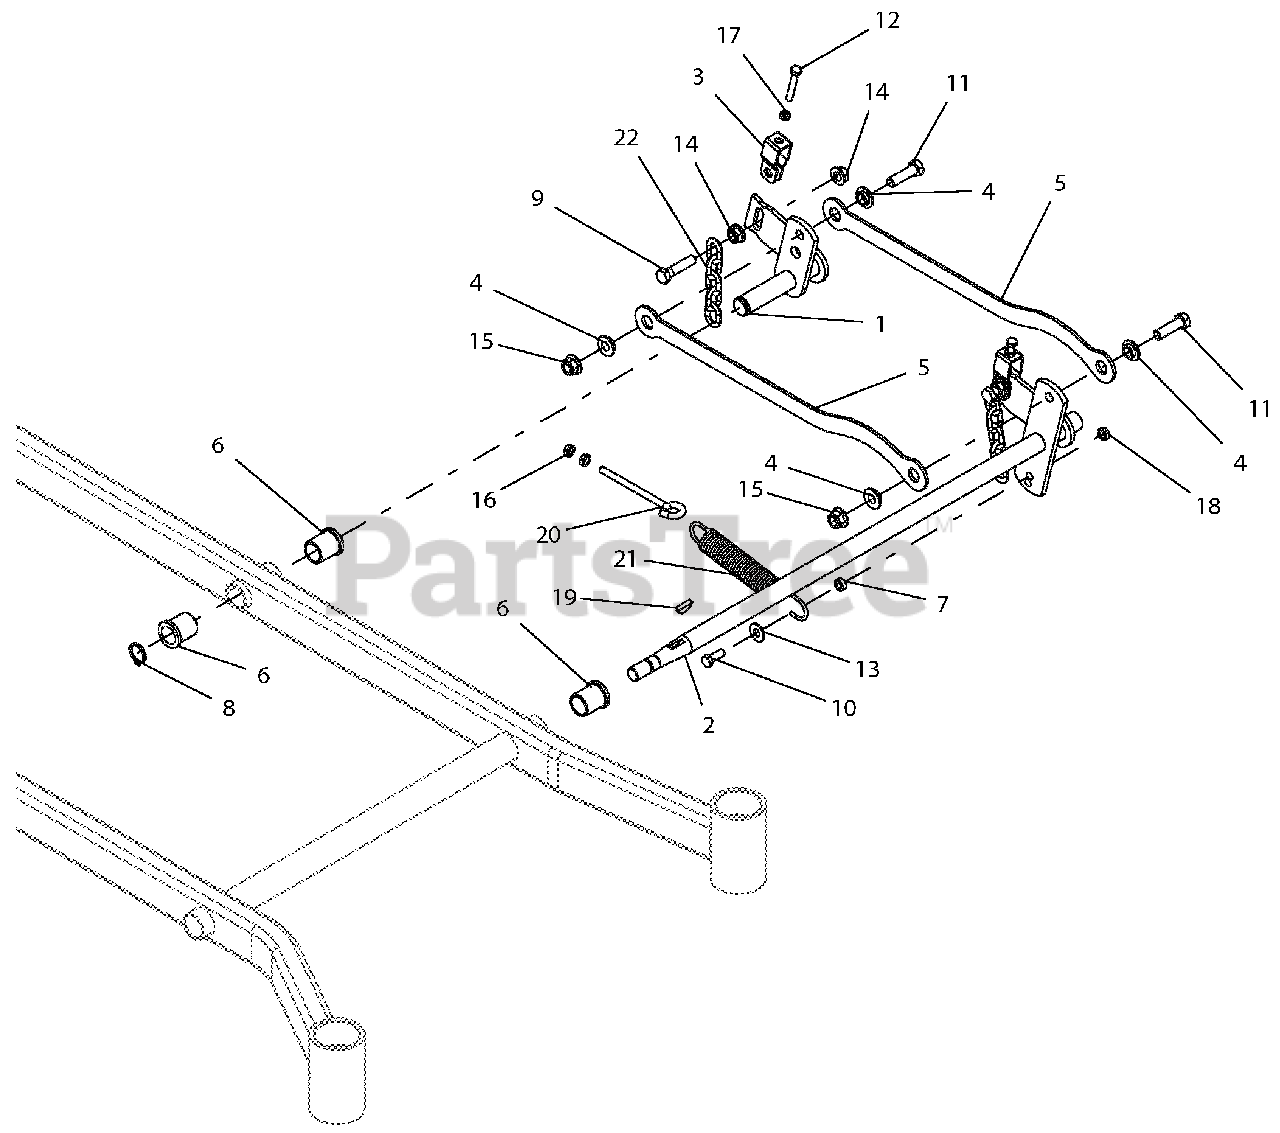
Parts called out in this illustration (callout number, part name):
1	WLDMT, REAR LH DECK LIFT
2	WLDMT, FRONT LH DECK LIFT ARM-BLACK
3	BRKT, DECK LEVELING
4	BSHG, FLANGE .515X.750X.31X1.12
5	LINK, LIFT - BLK
6	BSHG-FLG 1.00X1.25X1.5X1.5
7	BSHG, SLV .377X.624X.235
8	RG-RTNG-EXT 1.00X.078
9	BLT, HEX M12-1.75X50 CLS8.8 YZ
10	BLT-HEX .38-16X1.00 GR5 YWZC
11	BLT-HEX .50-13X1.75 GR5 YWZC
12	BLT-HEX .31-18X2.00 FTH GR5 YWZC
13	WSHR-FL-STL.438X1.00X.083 YWZC
14	NUT, SPLK -FLG M12-1.75 YZ
15	NUT-LK-NYL-FLG .50-13 YWZC
16	NUT, JAM .375-16 YWZC
17	NUT, JAM .312-18 YWZC
18	@NUT-LK-CTR-JAM .375-16 YWZC
19	KEY, WDRF .25 X 1.00 HRD #15
20	BOLT, EYE .38-16X6.00 .62 DIA
21	SPRG, TENSION .162 X 1.250 X 8.250
22	CHAIN, MOWER LIFT
